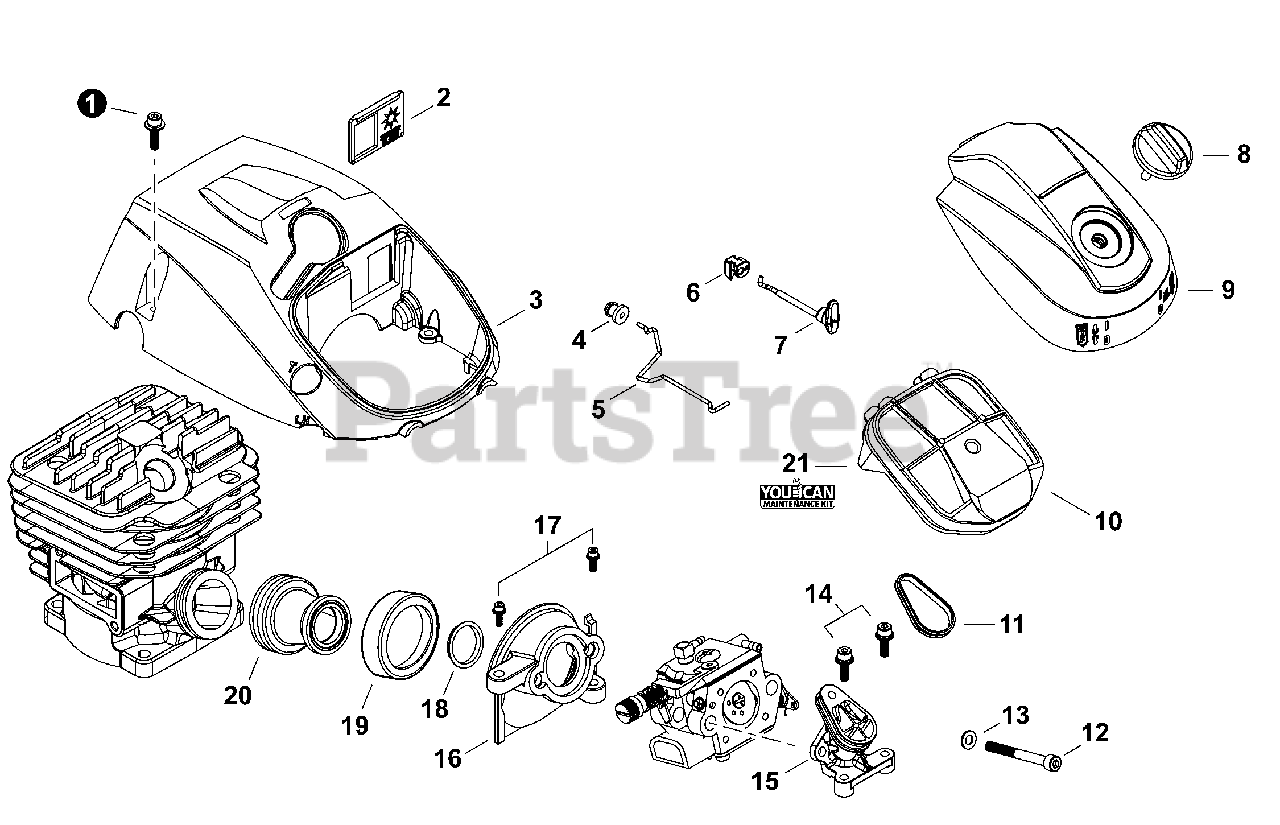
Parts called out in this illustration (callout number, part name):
1	BOLT M4×14
2	PLATE, SHUTTER
3	COVER, ENGINE
4	GROMMET
5	ROD, THROTTLE
6	GROMMET, CHOKE
7	ROD, CHOKE
8	THUMBSCREW
9	COVER, AIR FILTER
10	AIR FILTER ASSY, FLOCKED
12	BOLT M5×48
13	WASHER, FLAT 5.5×10×0.8
14	BOLT M4×16
15	ADAPTOR, AIR FILTER
16	INSULATOR, INTAKE
17	BOLT M4×16
18	COLLAR 16
19	HOLDER, BELLOWS
20	BELLOWS, INTAKE
21	TUNE-UP KIT - YOUCAN™
